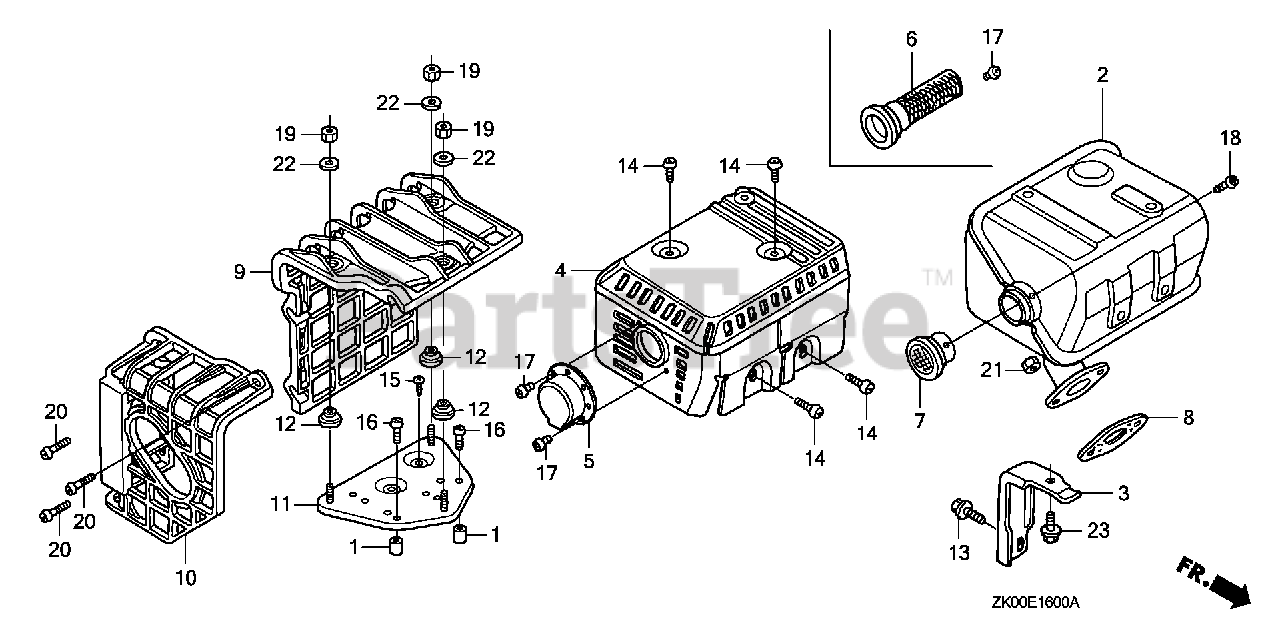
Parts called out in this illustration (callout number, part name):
3	STAY, MUFFLER
4	PROTECTOR, MUFFLER (SILENT)
6	ARRESTER, SPARK
7	NETTING, WIRE FLANGE
8	GASKET, MUFFLER
13	BOLT, FLANGE (6X13) (CT200)
14	SCREW, TAPPING (5X8)
17	SCREW, TAPPING (4X6)
18	SCREW, TAPPING (4X6)
21	NUT, HEX. (8MM)
23	BOLT, FLANGE (6X12)
